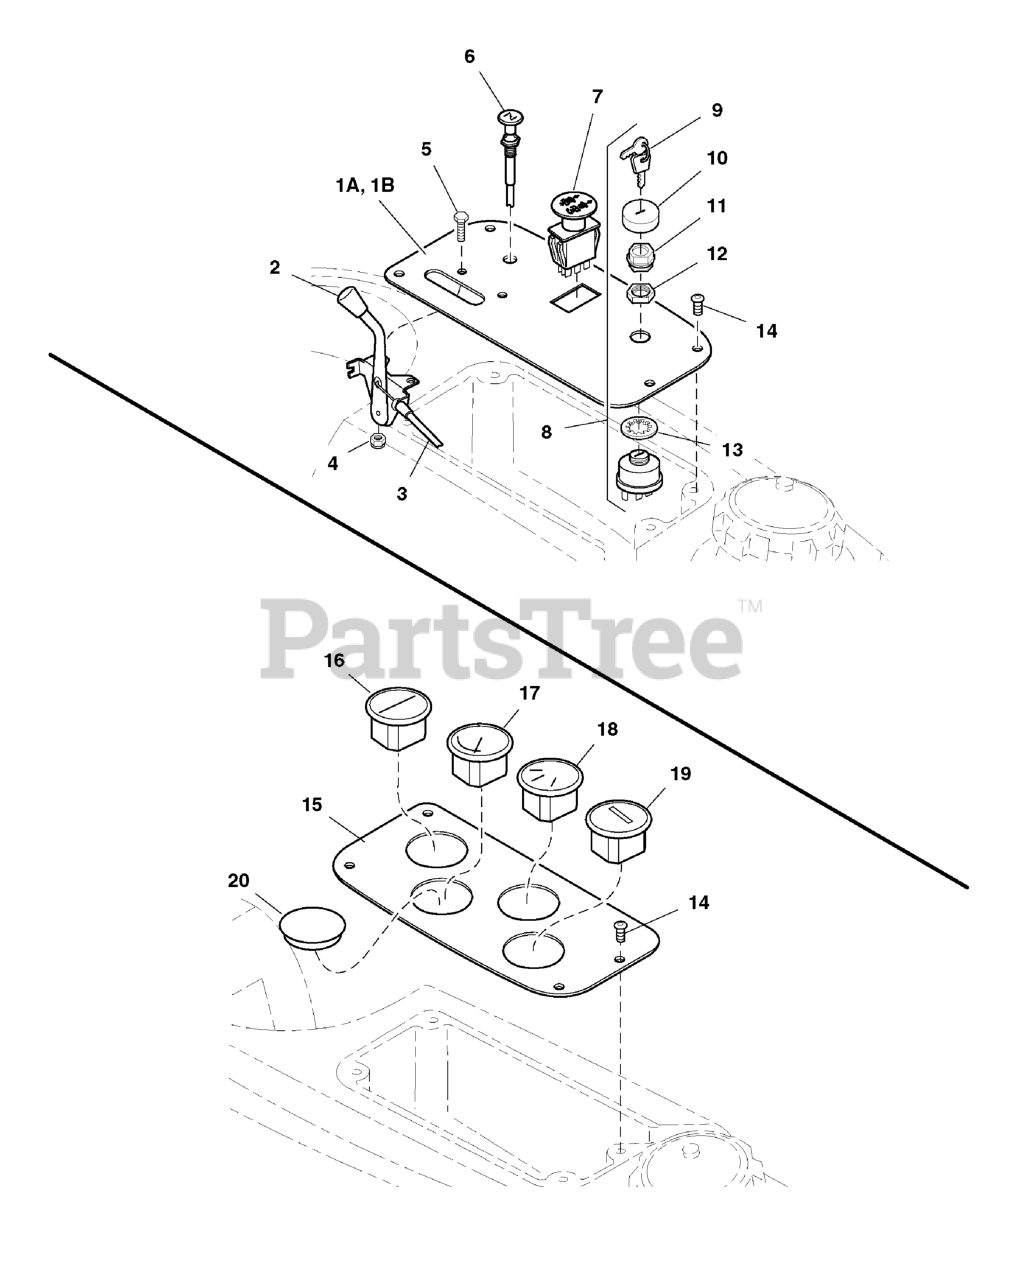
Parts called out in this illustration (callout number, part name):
1A	CONTROL PANEL-RH
1B	CONTROL PANEL-RH
2	HANDLE, THROTTLE CONTROL
3	CABLE, Throttle Control, 47-1/2"
3	CABLE, Throttle Control
4	NUT, 1/4-20 HEX NYLON LOCK
5	BOLT, 1/4-20 x 3/4
6	CABLE, Choke Control
6	CABLE, Choke Control, 47"
7	SWITCH, BLADE ENGAGEMENT
8	SWITCH, IGNITION, 6 POST
9	KEY, IGNITION MOLDED SET
10	COVER, PLASTIC, SNAP ON
11	PLASTIC NUT
12	STEEL NUT
14	SCREW, Allen Head, 1/4-20 x 1/2
15	PANEL, GAUGE CLUSTER (4)
16	GAUGE, Warning, Oil/Temp
17	GAUGE, Water Temperature
18	GAUGE, Voltmeter
19	HOUR METER
20	HOLE PLUG
